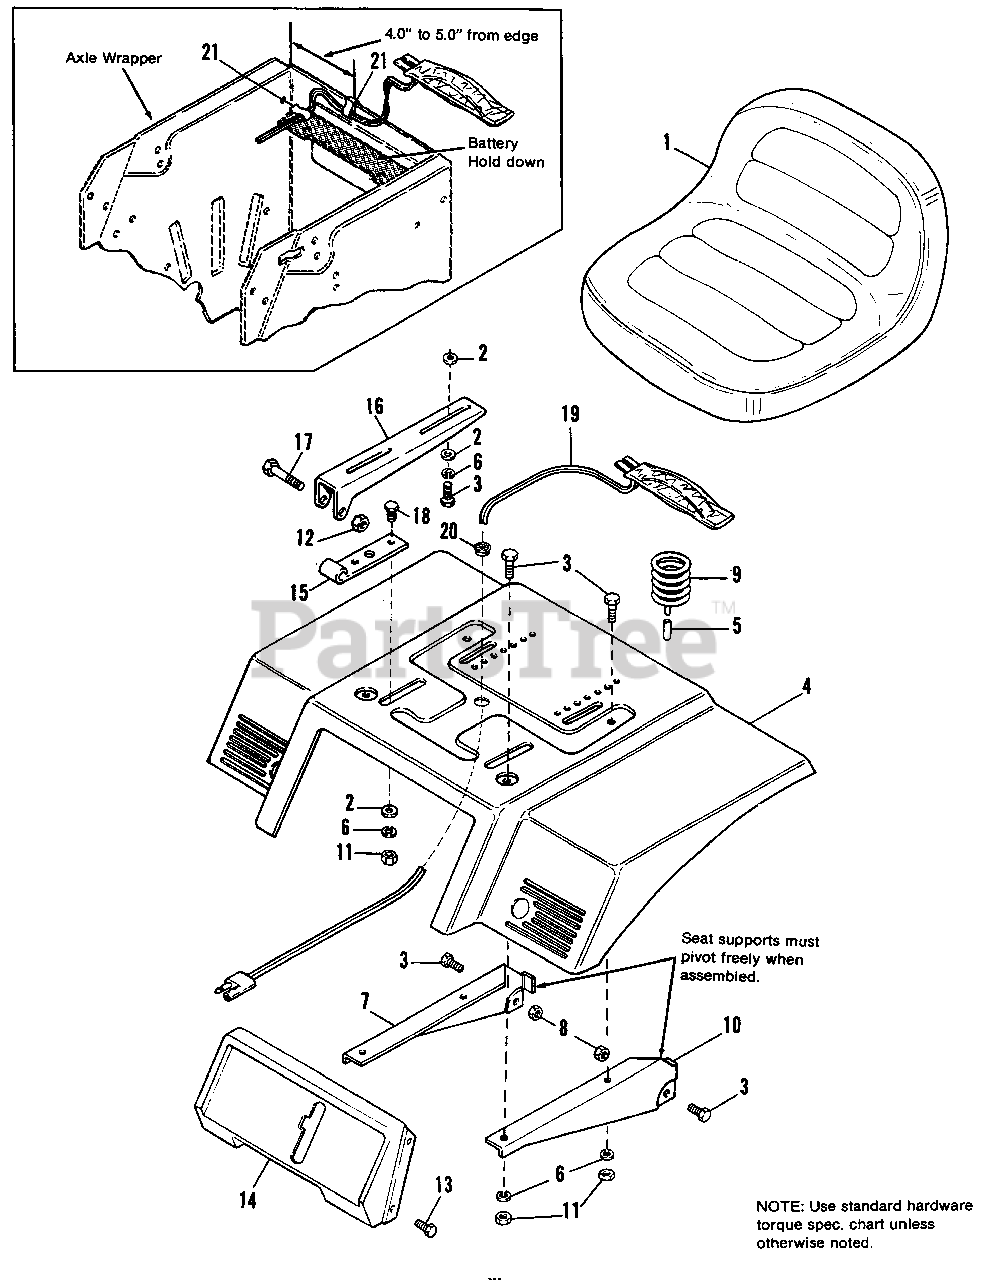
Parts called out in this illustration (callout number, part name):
2	WASHER, Plain, 5/16
3	CAPSCREW, Hex, 5/16-18 x 3/4
4	DECK, Seat
5	COVER, Wire
6	LOCKWASHER, 5/16
7	SUPPORT, Seat, R.H.
8	LOCKNUT, Hex, 5/16-18
9	SPRING, Seat
10	SUPPORT, Seat, L.H.
11	NUT, Hex, Full, 5/17-18
12	LOCKNUT, Hex, 3/8-16
13	SCREW, Hex, Taptite, 1/4-20 x 1/2
14	PANEL, Shift
15	HINGE, Lower
16	HINGE, Upper
17	CAPSCREW, Hex, 3/8-16 x 2
18	CAPSCREW, Hex, 5/16-18 x 1.0
19	SWITCH, Seat
20	BUSHING, Universal
